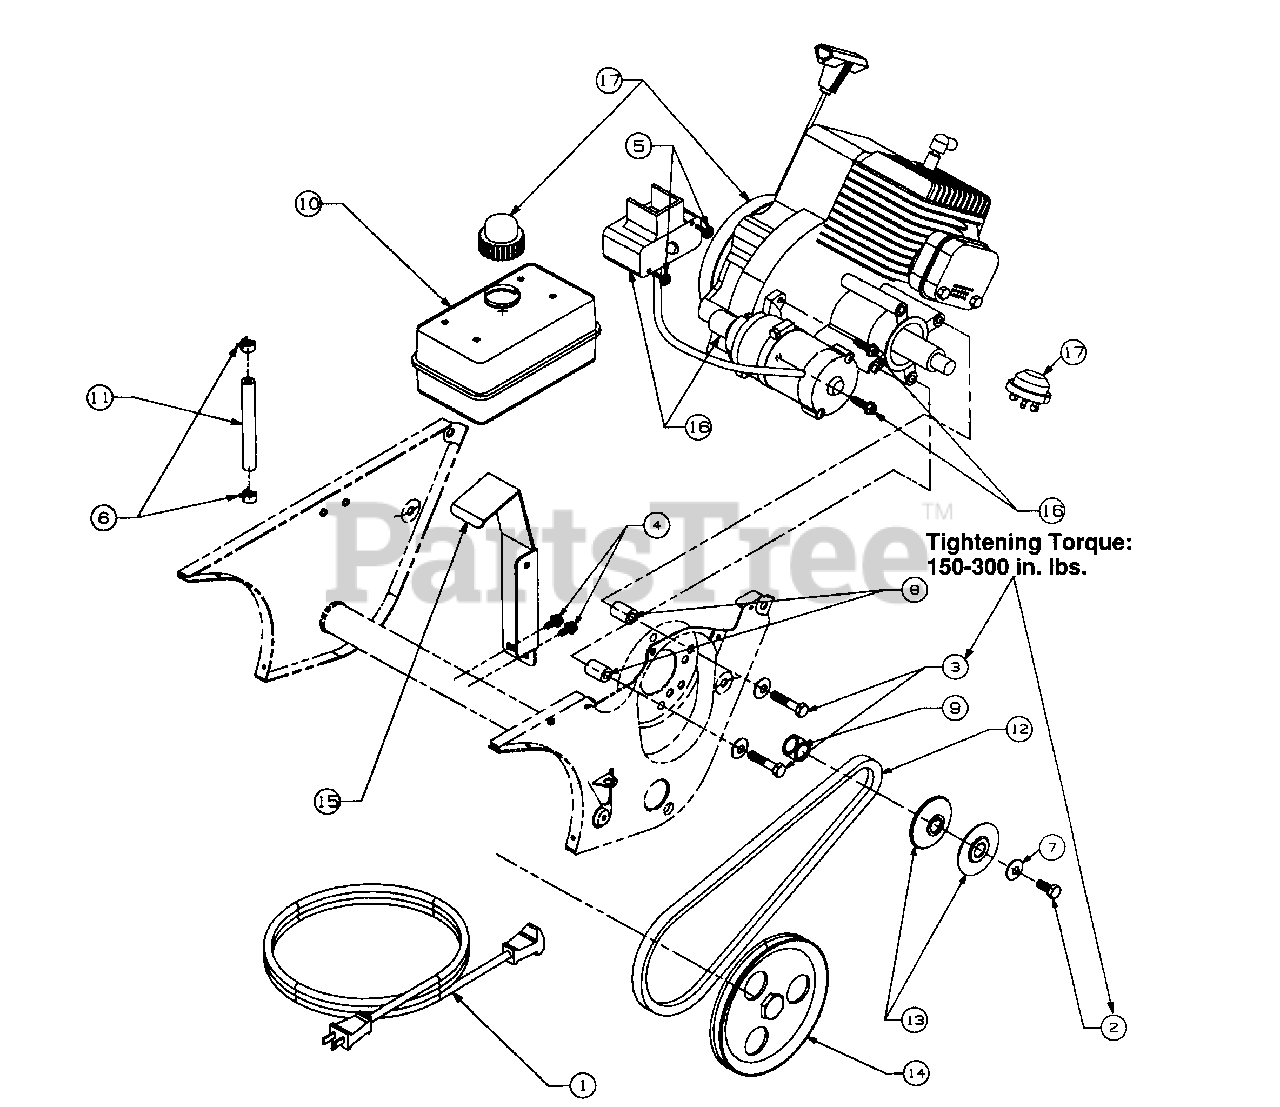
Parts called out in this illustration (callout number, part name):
1	Cord - Extension 110V3M 2 Prong
2	Screw - Hex Cap
3	Screw - Hex Cap
4	Screw - Washer
5	Screw - Hex
6	Hose Clamp
7	Washer - Bell
8	Spacer
9	Spacer
10	Tank - Fuel 1 Qt.
11	Hose - Fuel 12"
12	V-Belt
13	V-Pulley Half
14	Pulley
